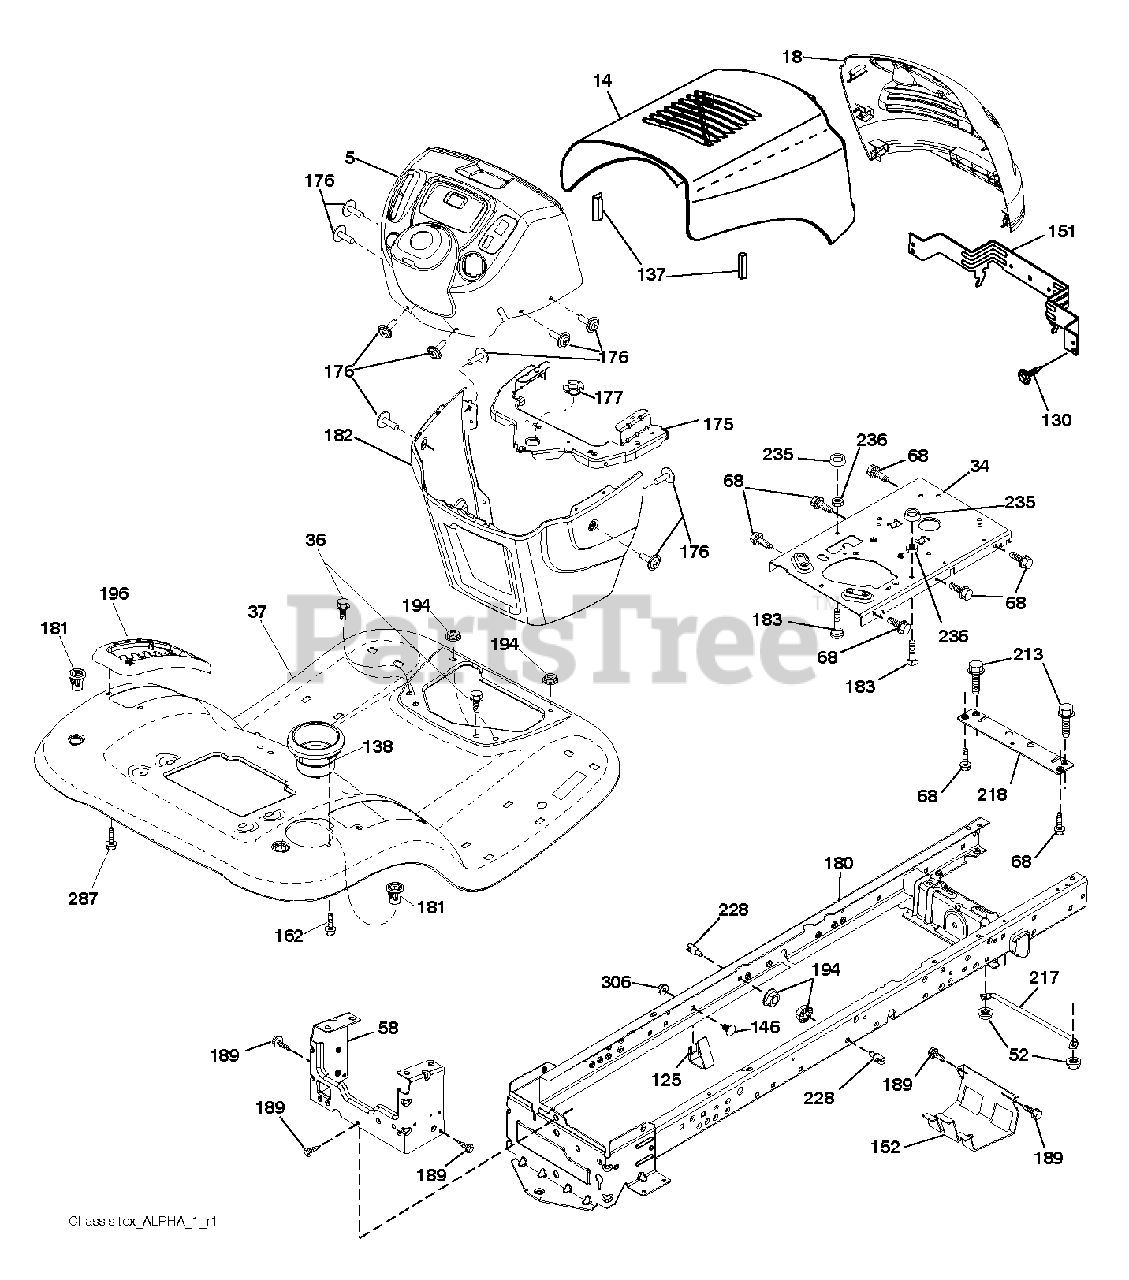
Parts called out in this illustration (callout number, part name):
5	DASH.P/L.TEX.CBL.CL.N/CHK.BLAC
14	HOOD.BLACK.ALPHA
18	GRILLE.SVC.BASE.PREDATOR.LT428
34	PLATE.ENGINE.WELDED.CHASSIS
36	SCREW 5/16"
37	FENDER.TLT.FS.W/CPH.428
52	LOCKNUT
58	DRAWBAR UPPER 2PC SMALL FENDER
68	SCREW LT
125	CLIP.FUEL.LINE
130	SCREW.#10 X 0.750.BOS (2 2)
137	BUMPER.HOOD.LARGE.1.75"
138	CUPHOLDER.TL.TEX.BLACK
146	BOLT.RDHD.SHT.SQNK.3/8-16X5/8
151	BRACKET.PIVOT.ALPHA.LT
152	SHIELD.BROWNING.W/TEX
162	SCREW.HI-LO.CONSOLE
175	CROSSMEMBER.LT
176	SCREW.#10-24X5/8.RN.QU
177	BUSHING STEERING
180	CHASSIS.WLDMNT.14GA.2PC.18".TI
181	FEND/FTRST.PCH.CPH.NFW
182	DASH.LOWER.LT.CCS
183	BOLT.5/16-18X1-1/4 FULL THD
189	SCREW
194	NUT LOCK HEX FLANGE 5/16-18
196	CONSOLE.ASM.DECKLFT.BL/RBT.TLT
213	BOLT
217	ROD.PIVOT.HOOD
218	X-PIECE.HOOD.STOP.NON/
228	STUD.FASTNER.W/ANTI-ROTATE
235	SPACER FENDER
236	NUT.CENTERLOCK.5/16-
287	SCREW 1/4X20
306	NUT LOCK FLG 3/8-16 UNC
